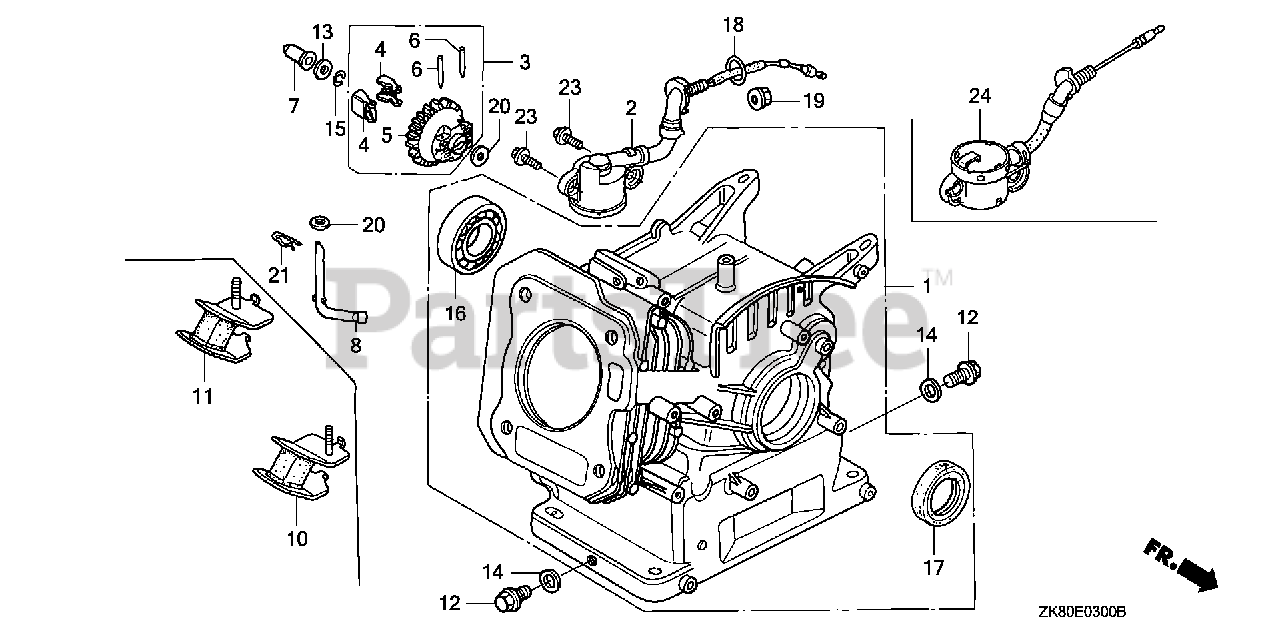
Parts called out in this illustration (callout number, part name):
1	CYLINDER ASSY. (OIL ALERT)
2	SWITCH ASSY., OIL LEVEL
3	GOVERNOR ASSY.
4	WEIGHT, GOVERNOR
5	HOLDER, GOVERNOR WEIGHT
6	PIN, GOVERNOR WEIGHT
7	SLIDER, GOVERNOR
8	SHAFT, GOVERNOR ARM
12	BOLT, DRAIN PLUG
13	WASHER, THRUST (6MM)
14	WASHER, DRAIN PLUG (10.2MM)
15	CLIP, GOVERNOR HOLDER
16	BEARING, RADIAL BALL (6205TMB) (NTN)
17	OIL SEAL (25X41X6)
18	O-RING (14MM) (ARAI)
18	O-RING (14MM) (NOK)
19	NUT, FLANGE (10MM)
20	WASHER, PLAIN (6MM)
21	PIN, LOCK (8MM)
23	BOLT, FLANGE (6X12)
